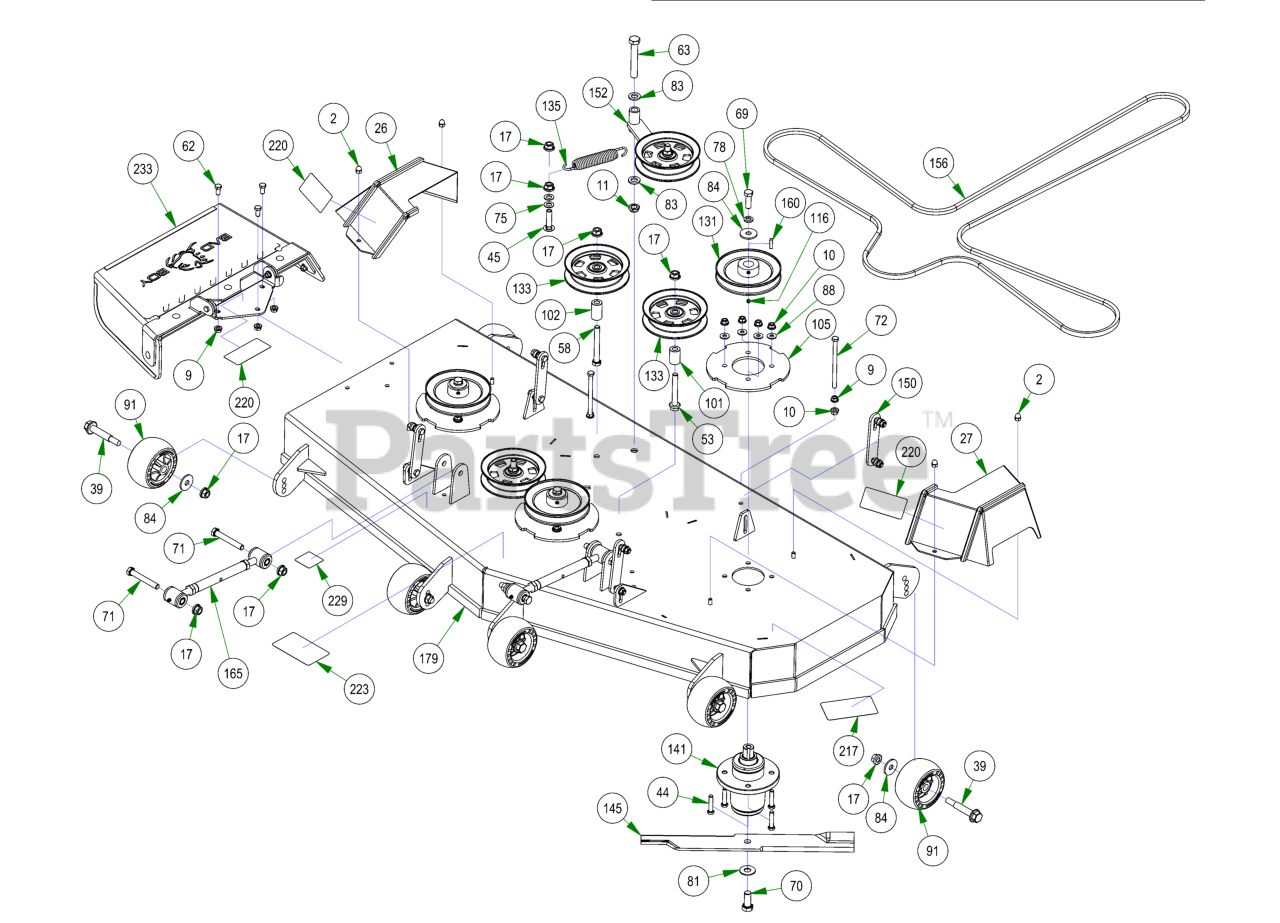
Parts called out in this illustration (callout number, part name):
2	5/16-18 ACORN NUT HIGH-CROWN ZC
9	3/8-16 HEX SERRATED FLANGE NUT HARD/ZINC
10	3/8-16 NYLON INSERT FLANGE LOCKNUT (GR.F) ZINC
11	5/8-11 NYLON INSERT JAM LOCKNUT ZINC
17	1/2-13 NYLON INSERT FLANGE LOCKNUT ZINC
26	2021 Maverick 54”/60” RH Pulley Cover
27	2021 Maverick 54”/60” LH Pulley Cover
39	Deck Wheel Bolt
44	3/8-16 X 1-3/4 HEX C/S (GR.5) ZC
45	1/2-13 X 2 CARRIAGE BOLT ZINC
53	1/2-13 X 3-1/2 HEX FLANGE BOLT (GR.8) ZINC
58	1/2-13 X 4 HEX CAP SCREW (GR.8) ZINC YELLOW
62	3/8-16 X 3/4 HEX CAP SCREW (GR.5) ZINC
63	5/8-11 X 4 HEX CAP SCREW (GR.8) ZINC YELLOW
69	1/2-20 X 1-1/2 HEX CAP SCREW (GR.5) ZINC
70	5/8-18 X 1-1/2 HEX CAP SCREW (GR.8) ZINC YELLOW
71	1/2-13 X 3-1/2 HEX CAP SCREW (GR.5) ZINC
72	3/8-16 X 5-1/2 HEX CAP SCREW (GR.5) ZINC
75	.517 SQ WDTH ID X .937 OD X .060 THICK F/W PHOS/OIL
78	1/2 SPLIT LOCKWASHER (GR.8) ZINC/YELLOW
81	5/8 USS FLAT WASHER (1-3/4" OD) GR.8 ZINC YELLOW
83	.635 ID X 1.120 OD X .140 THICK FLAT WASHER NYLON
84	1/2 BELLEVILLE WASHER (1-5/8 OD X .140 THK) ZINC
88	5/16 USS FLAT WASHER (7/8 OD) ZINC
91	Deck Wheel
101	.502 ID X .750 OD X 1.500 Long Spacer
102	1 3/4" Pulley Spacer
105	Deck Spindle Support Plate
116	5/16-24 X 1/4 SOCKET SET SCREW (CUP PT) PLAIN
131	6 1/4" Drive Pulley
133	5-3/4 Idler Pulley
135	Deck Idler Spring
141	OUTLAW SPINDLE ASSEMBLY
145	60" High Lift Fusion Blade
150	Deck Hanger Assembly
152	2017 MZ/ZT Deck Idler Assembly
160	1/4 X 1 SQ MACHINERY KEY 1018 STL PLN
165	2018 Maverick Turnbuckle (Top Link)
179	2017 60" ZT Deck Welded Assembly
217	2018 60" Deck Decal
220	Danger Decal-Spindle/Discharge
223	Deck Belt Route Decal
229	Deck Impact Patent Decal 9591803
233	Discharge Chute Assembly
